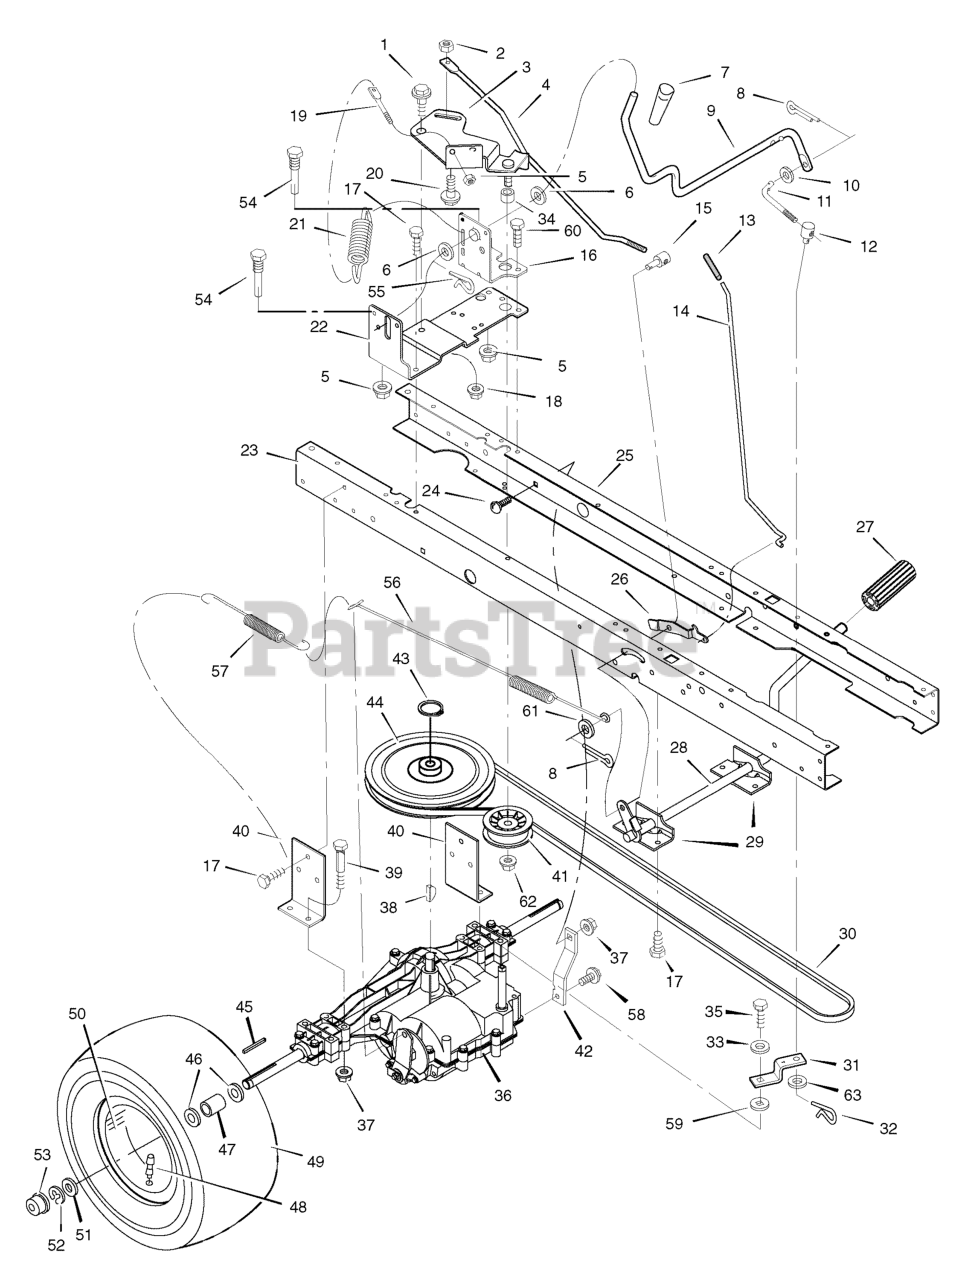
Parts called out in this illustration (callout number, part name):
1	Bolt, Shoulder
2	Nut, Hex
3	ARM, Idler
4	Rod, Clutch
5	Nut
6	Washer
7	Grip
8	Pin, Cotter
9	Lever, Shift
10	Washer
11	Link, Shift
12	Nut, Adjuster
14	Rod, Parking Brake
15	Nut, Adjuster
16	Bracket, Shift Pivot
18	Nut
19	Mount, Stud Spring
20	Bolt, Shoulder
21	Spring, Extension
22	Bracket, Right Shifter
23	Frame, Right
24	Bolt, Carriage
25	Frame, Left
26	Latch, Parking Brake
27	Pedal
28	Lever, Brake/Clutch
29	Bracket, Pedal
30	Belt, Motion Drive
31	Yoke, Shift
32	Pin, Hair
36	Transaxle **
37	Nut
38	Key, Woodruff
39	Bolt
40	Bracket, Transaxle
42	BRACKET, Torque Strap, LH
43	Ring Retainer
44	Pulley, Drive
45	Key, Square
47	SPACER, Rear Wheel
48	Stem, Valve
50	Wheel & Tire Assembly
53	Hub Cap
54	Guide, Belt
55	Pin, Hair
56	Spring, Extension
57	Spring, Extension
61	Washer
62	Washer
63	Washer
